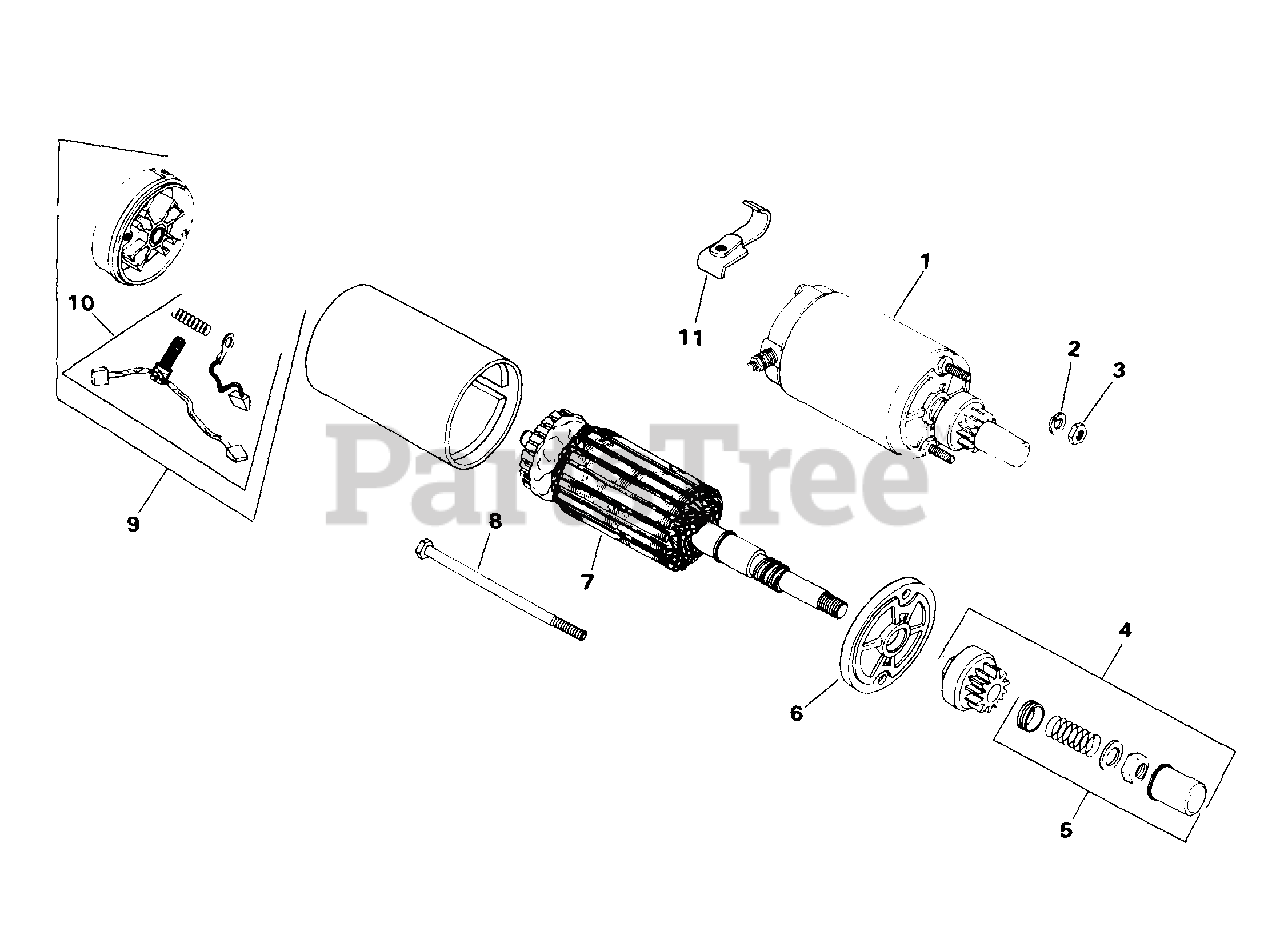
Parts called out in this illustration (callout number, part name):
1	STARTER - USE 52 098 12
2	WASHER, SPRING LOCK 1/4"
3	NUT, 1/4-20 GRADE 2 USE 25 100 20-S
4	DRIVE KIT - USE 82 755 32
5	DRIVE - USE 82 755 32
6	KIT - USE 82 755 32
7	ARMATURE - (#DSC)
9	CAP - USE 52 227 10
10	KIT - USE 52 755 15
2545003-S	TAG, CAUTION
5235701-S	Lubricant, Inertia Drive Starter (0.25 oz.)
